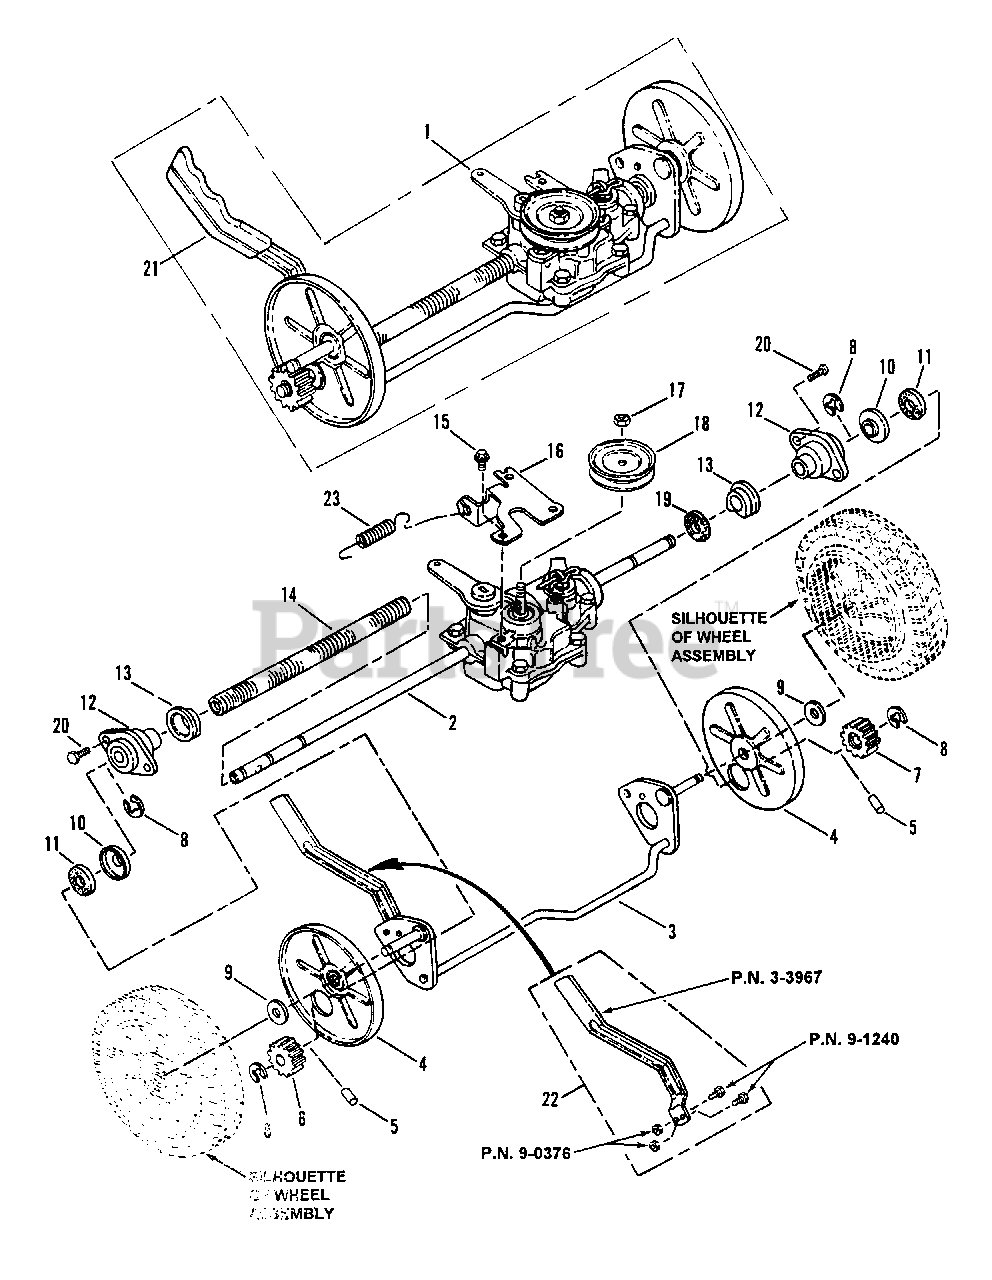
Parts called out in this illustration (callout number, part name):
1	AXLE/TRANSMISSION ASSEMBLY
2	ASSEMBLY, Transmission
3	ASSEMBLY, Rear Axle Weldment
4	SHIELD, Dust
5	PIN, Pawl, 3/16 O.D.
6	PINION, Right Hand Drive
7	PINION, Left Hand Drive
8	RING, Retaining
9	WASHER, .531 I.D. x 1.50 O.D.
10	RETAINER, Pinion Seal
11	SEAL, Pinion (Felt)
12	ASSEMBLY, Bearing Carrier
13	BUSHING, Rear Axle
14	TUBING, 5/8" I.D., Convoluted
15	SCREW, 5/16-18 x 5/8 Hex Washer Head, Self-Tapping
16	BRACKET, Transmission
17	NUT, M10-1.50 Hex Nyloc
18	PULLEY, Transmission
19	WASHER, Felt
20	SCREW, 1/4-20 x 3/8" Hex Washer Head, Self-Tapping
21	GRIP, Height Adjust Lever
22	KIT, Height Adjusting Lever
23	SPRING, Transmission Extension
